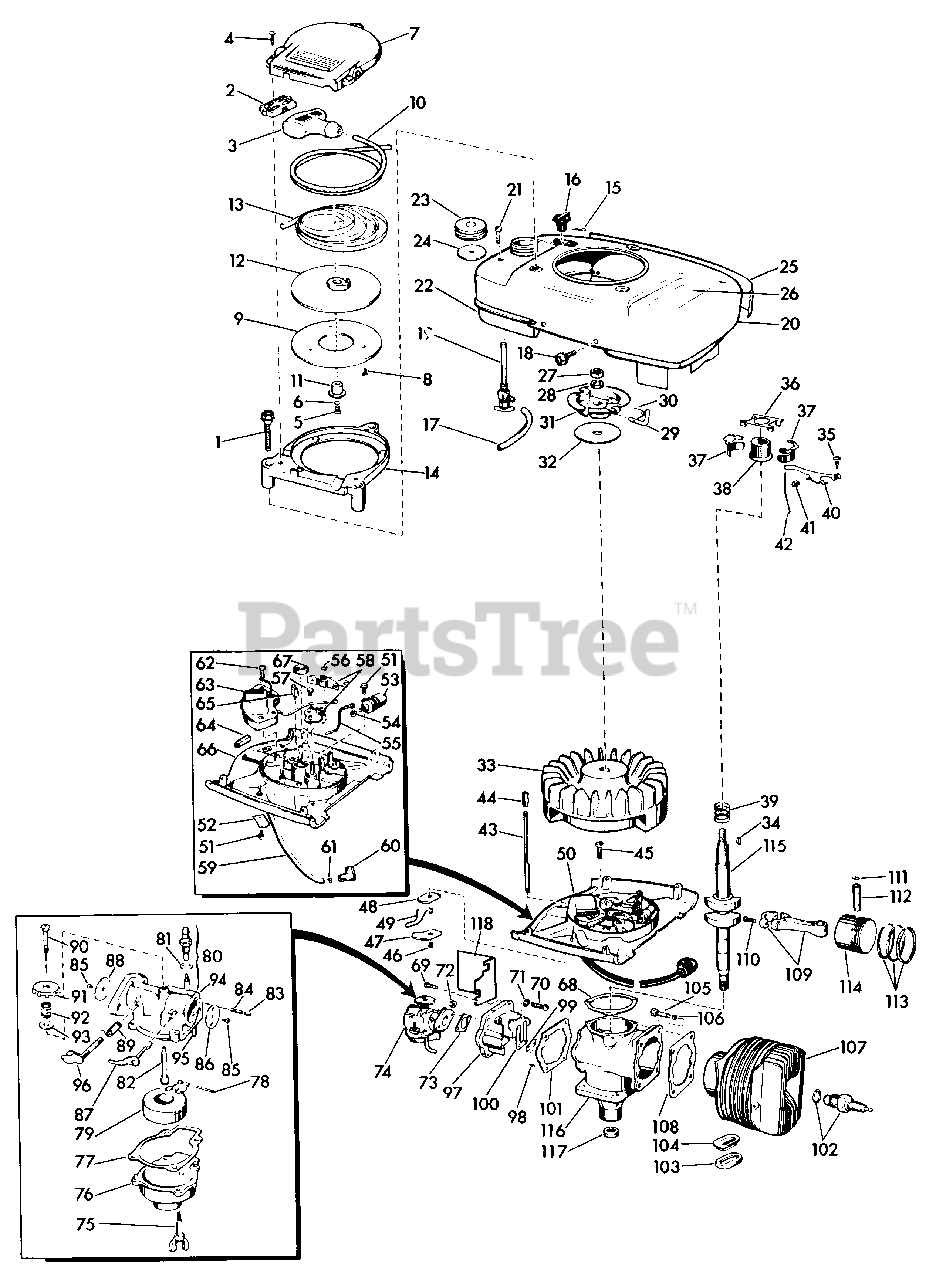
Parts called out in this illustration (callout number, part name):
1	Screw-Starter to Shroud
2	Anchor-Rope
3	Handle-Starter
4	Screw-Starter Cap to Base
5	Screw-Pulley to Cap
6	Lockwasher-Pulley to Cap
7	Cap-Starter
8	Screw-Pulley Plate
9	Plate-Pulley
10	Rope-Starter
11	Bearing-Pulley
12	Pulley-Rewind
13	Spring-Recoil
14	Base-Starter
15	Pin-Choke Knob Cotter
16	Knob-Choke Bar
17	Line-Gas
18	Screw-Shroud to Armature Plate
19	Shut-off Valve and Screen Assembly
20	Shroud and Shield Assy
21	Screw-Machine
22	Gas Tank Assembly
23	Gas Cap and Gasket Assy
24	Gasket-Gas Cap
25	Decal-"Snow-Boy"
26	Decal-Instruction
27	Nut-Flywheel
28	Lockwasher-Flywheel
29	Pin-Starter
30	Spring-Starter Pin
31	Pulley-Flywheel
32	Washer-Flywheel
33	Flywheel Assembly
34	Key-Woodruff
35	Screw-Governor
36	Yoke-Governor
37	Weight-Governor
38	Collar-Governor
39	Spring-Governor
40	Governor Lever and Wear Block Assembly
41	Wear Block-Governor
42	Rod-Governor
43	Bar-Choke
44	Sleeve-Choke Bar
45	Screw-Crankcase to Armature Plate
46	Screw-Shut-off Switch
47	Insulator-Shut-off, Lower
48	Insulator-Shut-off, Upper
49	Spring-Shut-off Switch
50	Armature Plate Assembly
51	Screw-Condenser and Clamp Mounting
52	Clamp-High Tension Lead
53	Condenser Assembly
54	Nut-Condenser Terminal
55	Shut-off Switch Lead Assy
56	Clip-Spring, Breaker Post
57	Screw-Breaker Base
58	Breaker Base and Arm Assy
59	High Tension Lead Assy
60	Cover-Rubber, Spark Plug
61	Terminal-Spring
62	Screw-Lamination Mounting
63	Coil and Lamination Assembly
64	Pad-Rubber, Armature Plate
65	Wick-Oiler
66	Armature Plate, Bearing and Oil Seal Assembly
67	Seal-Oil
68	Gasket-Crankcase to Armature Plate, .005 in.
68	Gasket-Crankcase to Armature Plate, .010 in.
69	Screw-Reed Plate to Crankcase
70	Screw-Reed Plate to Carburetor
71	Washer-Reed Plate to Carburetor Screw
72	Nut-Stop, Reed Plate to Carburetor Screw
73	Gasket-Carburetor
74	Carburetor Assembly
75	Screw-Float Chamber
76	Float Chamber
77	Gasket-Carburetor Body to Float Chamber
78	Pin-Float Arm Hinge
79	Float and Arm Assembly
80	Float Valve, Seat and Washer Assembly
81	Washer, Float Valve Seat
82	Nozzle
83	Plug-Choke Friction
84	Spring-Choke Friction
85	Screw-Choke and Throttle Disc
86	Disc-Choke
87	Choke Shaft and Lever Assy
88	Disc-Throttle
89	Spring-Throttle Shaft
90	Needle Assembly
91	Knob, Needle Valve
92	Spring, Needle Adjustment
93	Washer, Needle Adjustment
94	Carburetor Body
96	Throttle Shaft
97	Reed Plate Assembly
98	Screw-Reed to Reed Plate
99	Plate-Reed Back-up
101	Gasket-Reed Plate to Crankcase
102	Spark Plug and Gasket
103	Gasket-Exhaust
104	Sleeve-Exhaust Gasket
105	Screw-Cylinder to Crankcase
106	Washer-Lock, Cylinder to Crankcase
107	Cylinder and Sleeve Assembly
108	Gasket-Cylinder to Crankcase
109	Connecting Rod Assembly
110	Screw-Connecting Rod
111	Ring-Spring
112	Pin-Wrist
113	Ring Set-Piston
115	Crankshaft
116	Crankcase Oil Seal and Bearing Assembly
117	Seal-Oil
118	Shield-Carburetor
